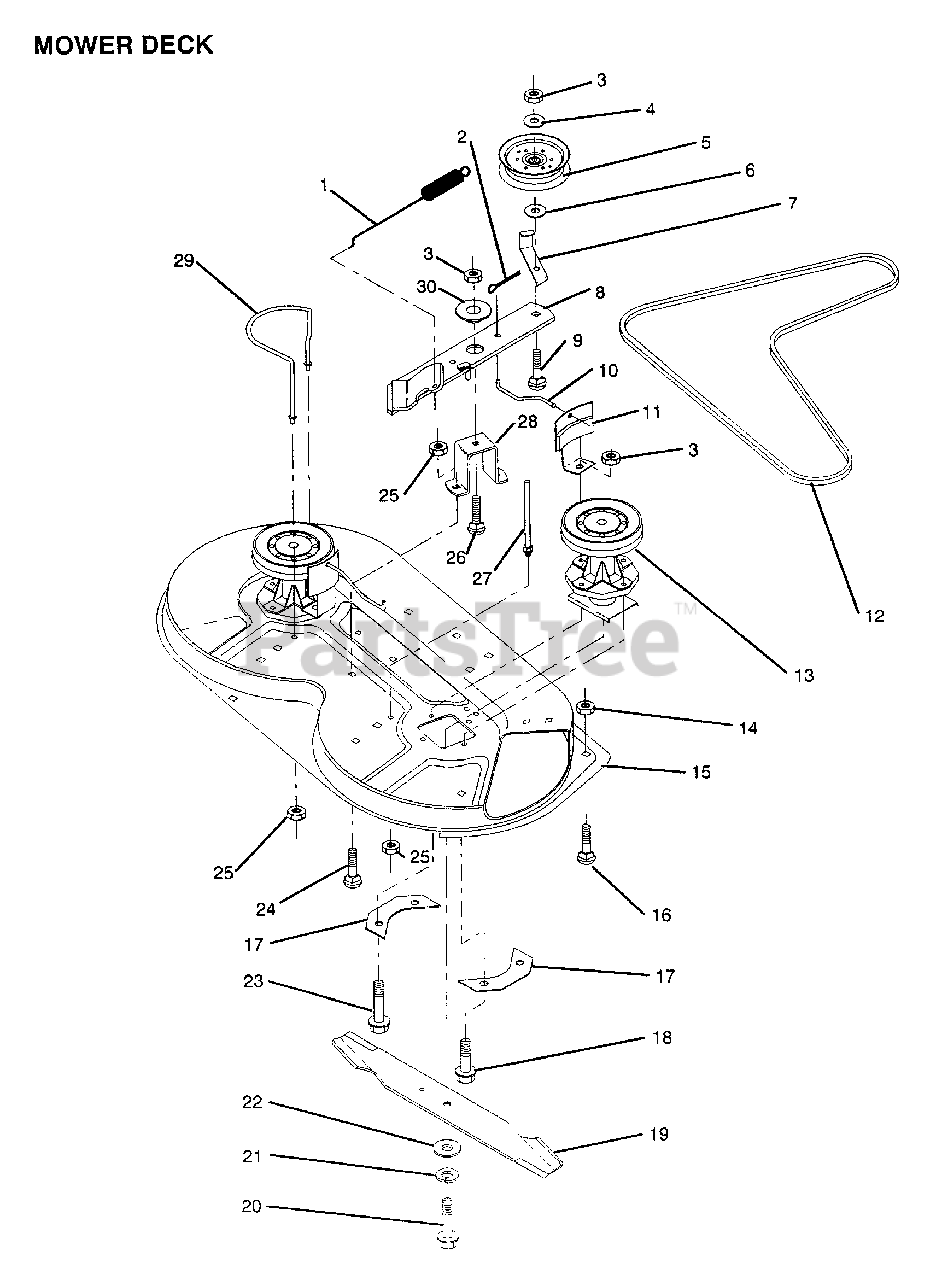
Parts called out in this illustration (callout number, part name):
4	WASHER
5	PULLEY IDLER
6	WASHER GT
8	IDLER ARM ASS'Y
9	BOLT CARRIAGE
10	ROD BRAKE
11	BRAKE LT
12	BELT.MOWER.79.75
13	MANDREL ASS'Y
16	BOLT
17	SUPPORT PLATE LT
18	SCREW
19	"BLADE.36""HIGH LIF"
20	BOLT.3/8-24X1-1/2
22	WASHER
23	SCREW
24	BOLT
26	BOLT D
27	"GUIDE,REAR BEL RH"
28	"SUPT,IDLER ARM"
29	GUIDE BELT LH
30	SPACER RETAINER
